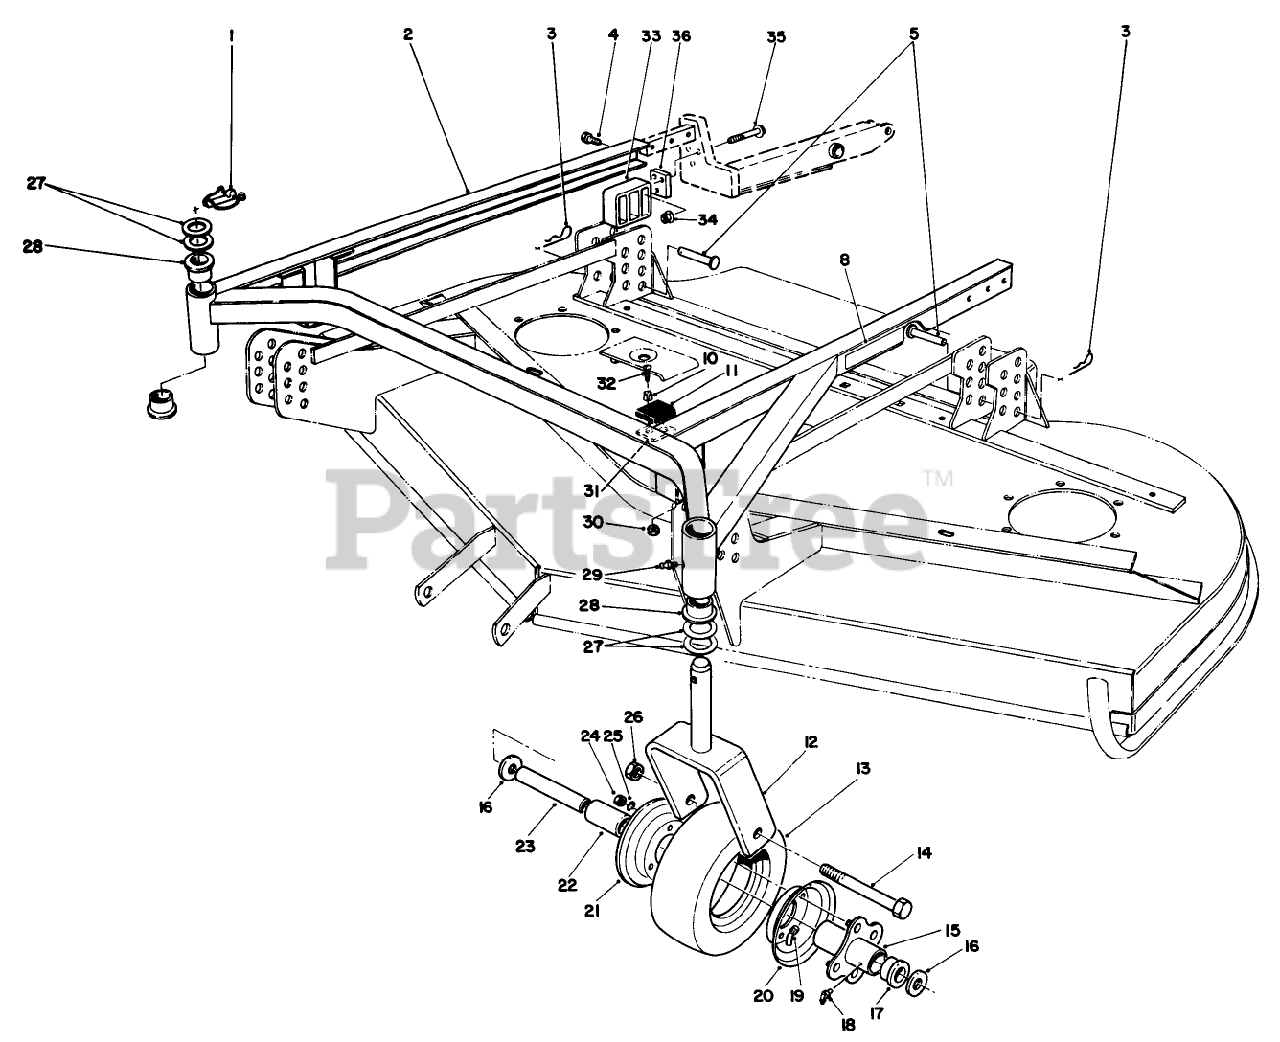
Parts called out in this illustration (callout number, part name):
1	PIN-LYNCH
2	Frame Assembly (Incl. Ref. #28)
3	PIN-HAIR
4	SCREW-HH
5	PIN-CLEVIS
8	DECAL - HEIGHT-OF-CUT
10	SPACER
11	CUSHION-RUBBER
12	Castor Fork
14	SCREW-HH
15	HUB-CENTER
16	WASHER-FLAT
17	BEARING-OUTSIDE
18	FITTING-GREASE
19	TUBE-INNER (W/VALVE)
20	FEMALE WHEEL HALF
21	MALE WHEEL HALF
22	BEARING-ROLLER
23	SPANNER-TIRE
24	NUT-HEX
25	WASHER-LOCK
26	NUT-HEX
27	WASHER-THRUST
28	Bushing
29	FITTING-GREASE
30	NUT-LOCK, NI
31	SHIM-CUSHION
33	Cradle-Rear
34	NUT-FLANGE
35	SCREW-HHF, WHIZ
36	Spacer
